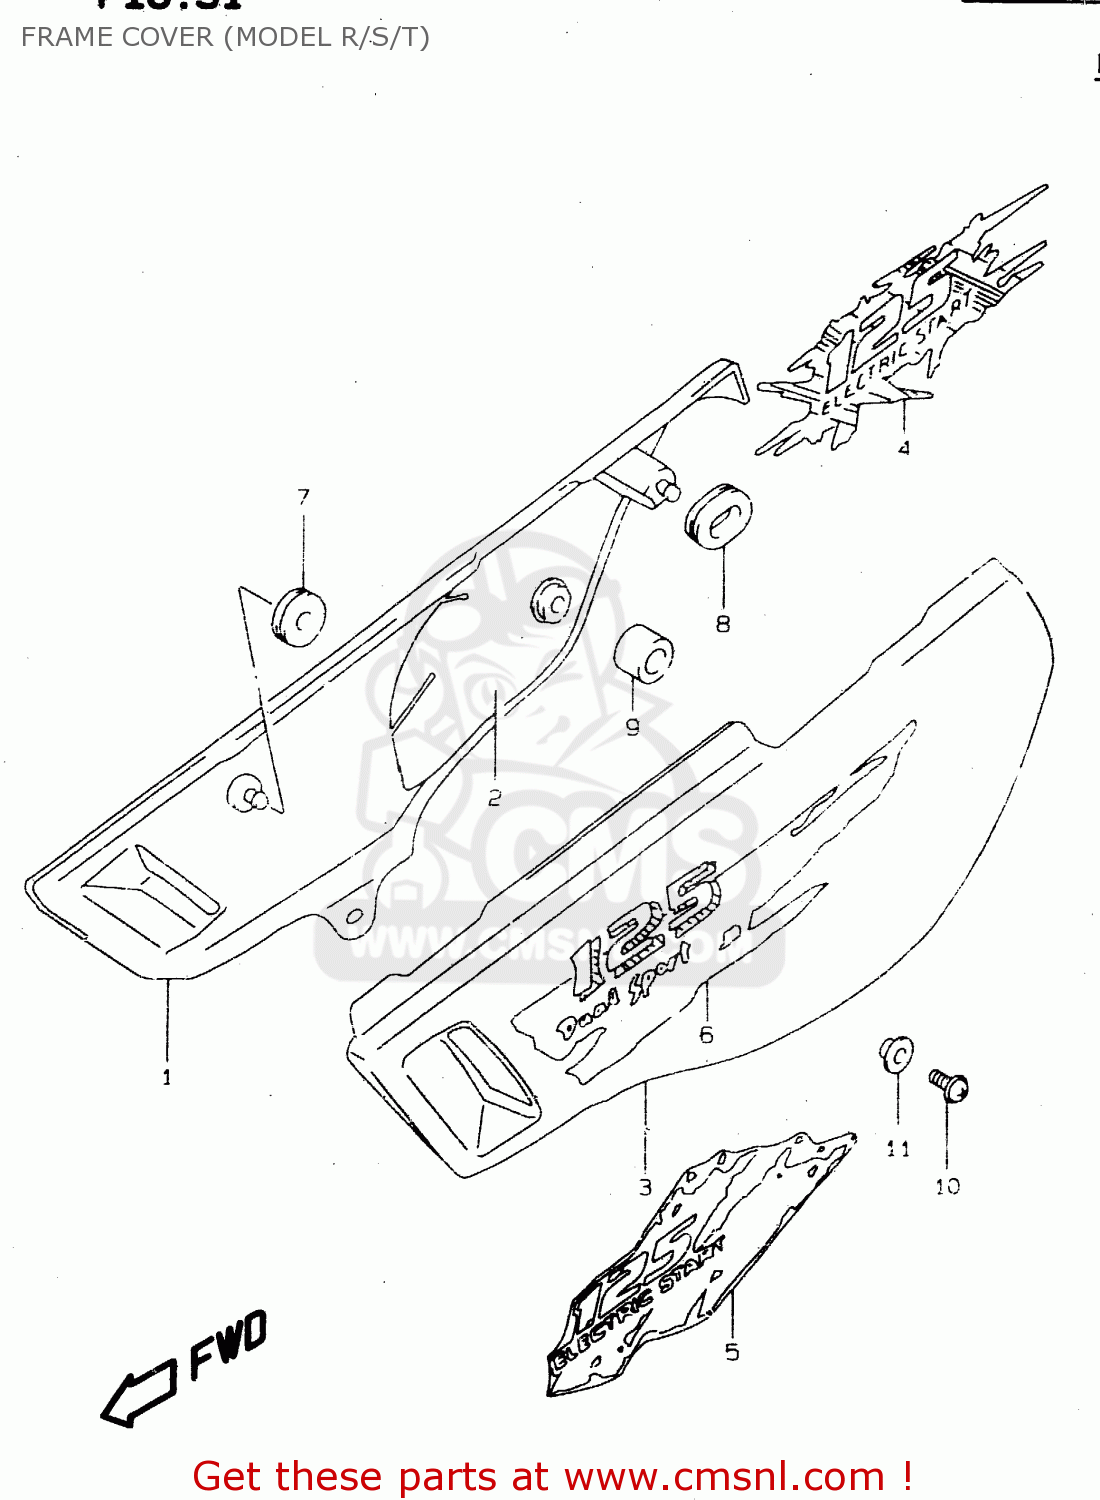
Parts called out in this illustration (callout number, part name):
1	COVER,FRAME,R(WHITE)
2	SHIELD,FRAME COVER,R
3	COVER,FRAME,L(WHITE)
4	EMBLEM, FRAME COVER
5	TAPE,FRAME COVER
6	TAPE,FRAME COVER,R
7	CUSHION
8	CUSHION
9	CUSHION
10	SCREW(6X16)
11	WASHER
